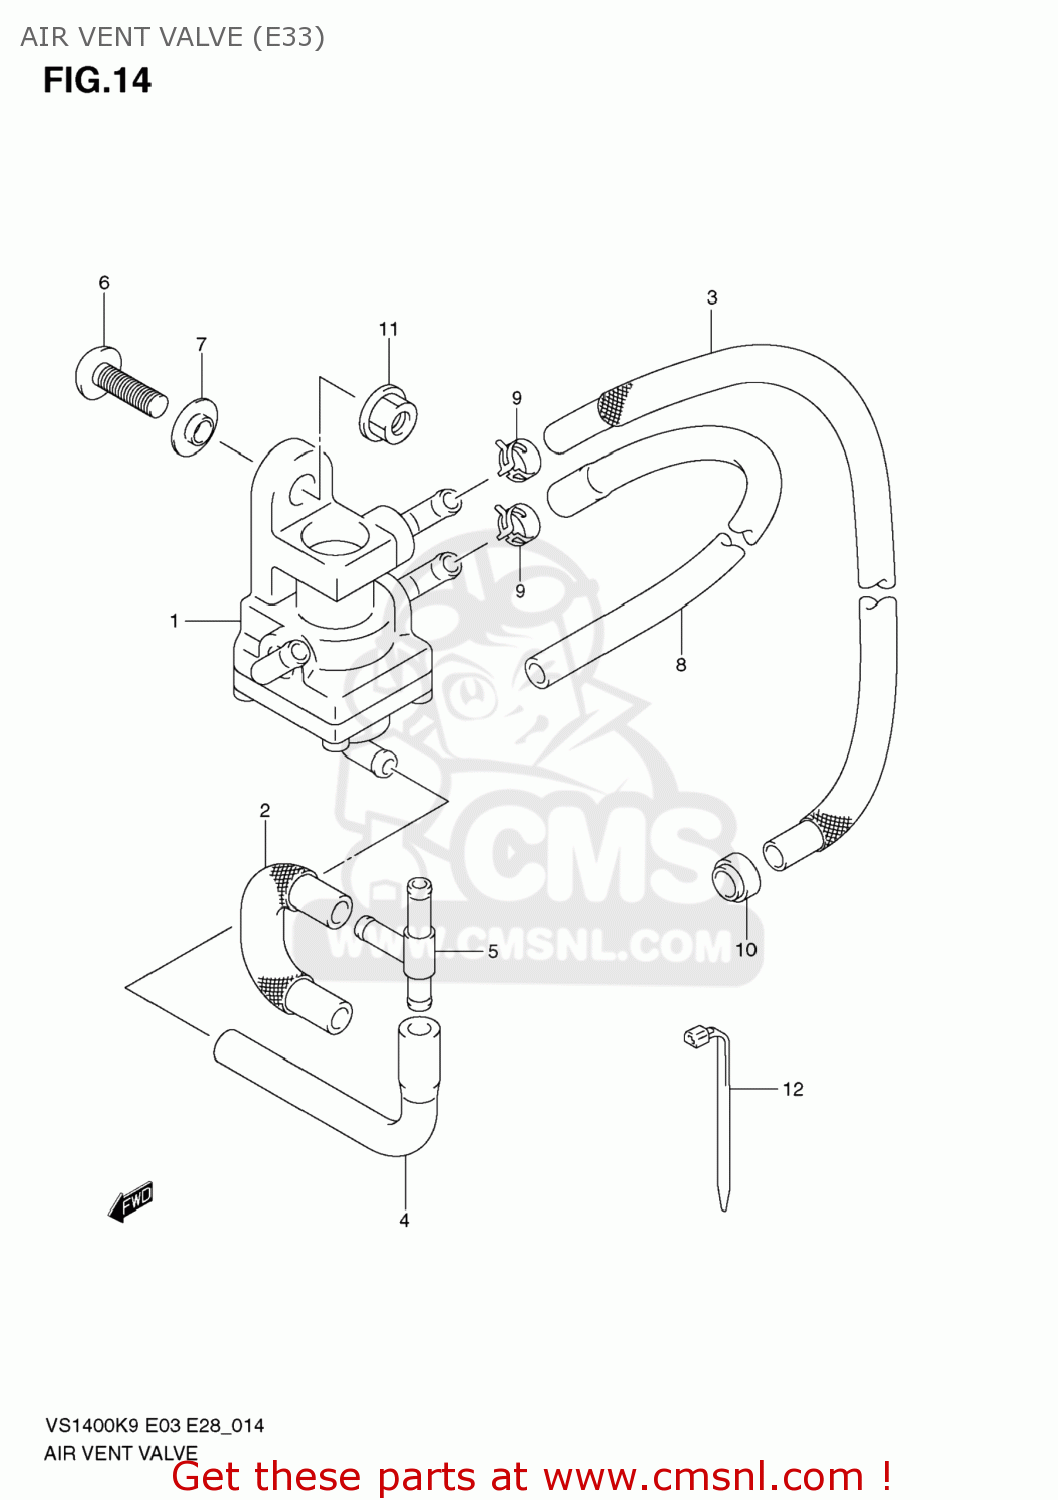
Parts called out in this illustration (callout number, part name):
1	VALVE COMP,AIR VENT
2	HOSE,INTAKE VACUUM
3	HOSE,AIR VENT VALVE
4	HOSE,AIR VENT VALVE VACUUM
5	3 WAY
6	SCREW(6X20)
7	WASHER
8	HOSE(5X10X600)
9	CLIP
10	CLIP
11	NUT
12	CLAMP(L:165)
